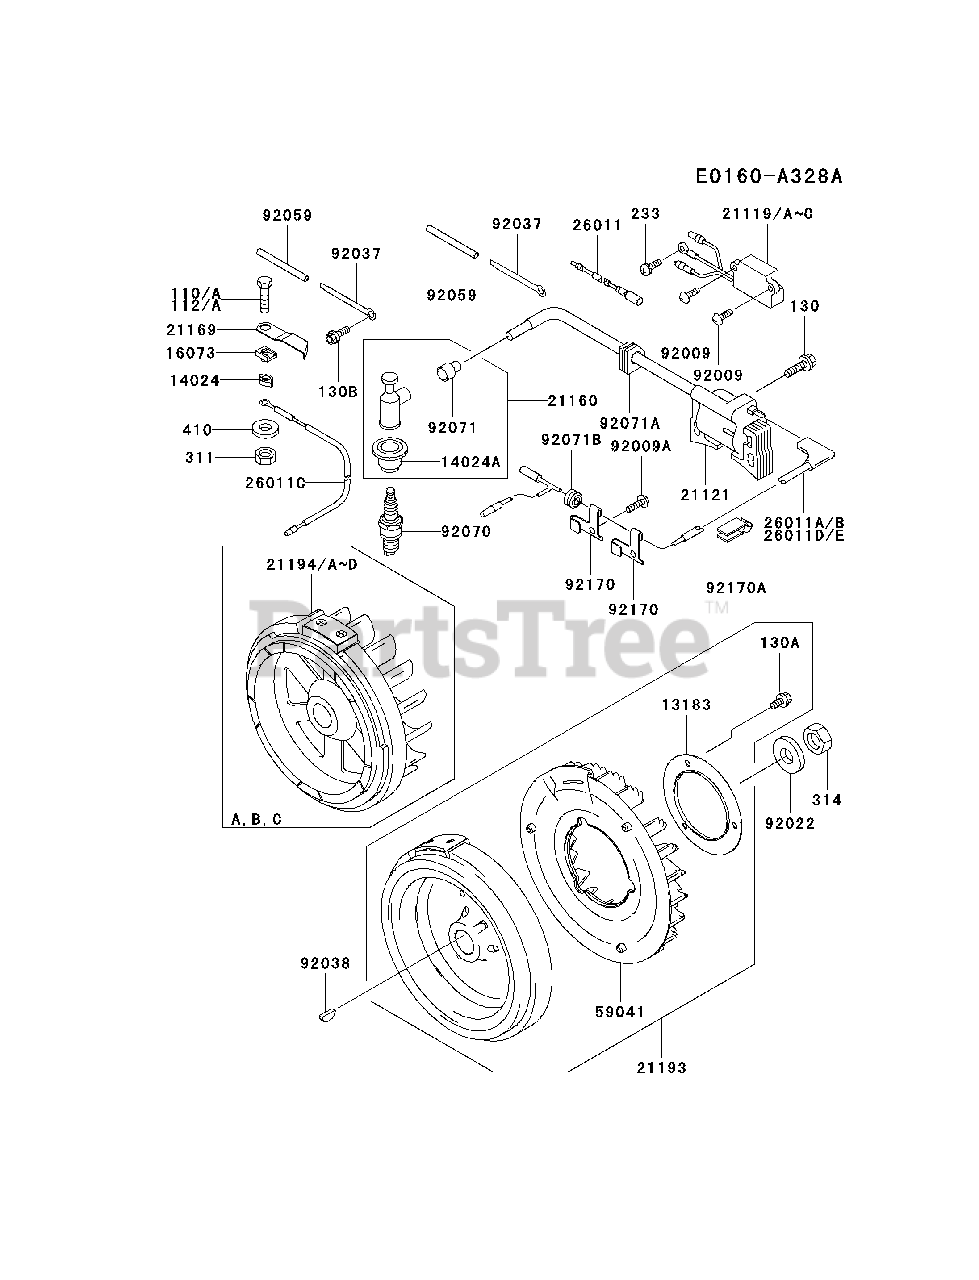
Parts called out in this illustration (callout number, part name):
112	BOLT-UPSET
130	BOLT-FLANGED
130A	BOLT-FLANGED
130B	BOLT-FLANGED
233	SCREW-PAN-WP+-
311	NUT-HEX
314	NUT-HEX-FINE
410	W-PLAIN-S
